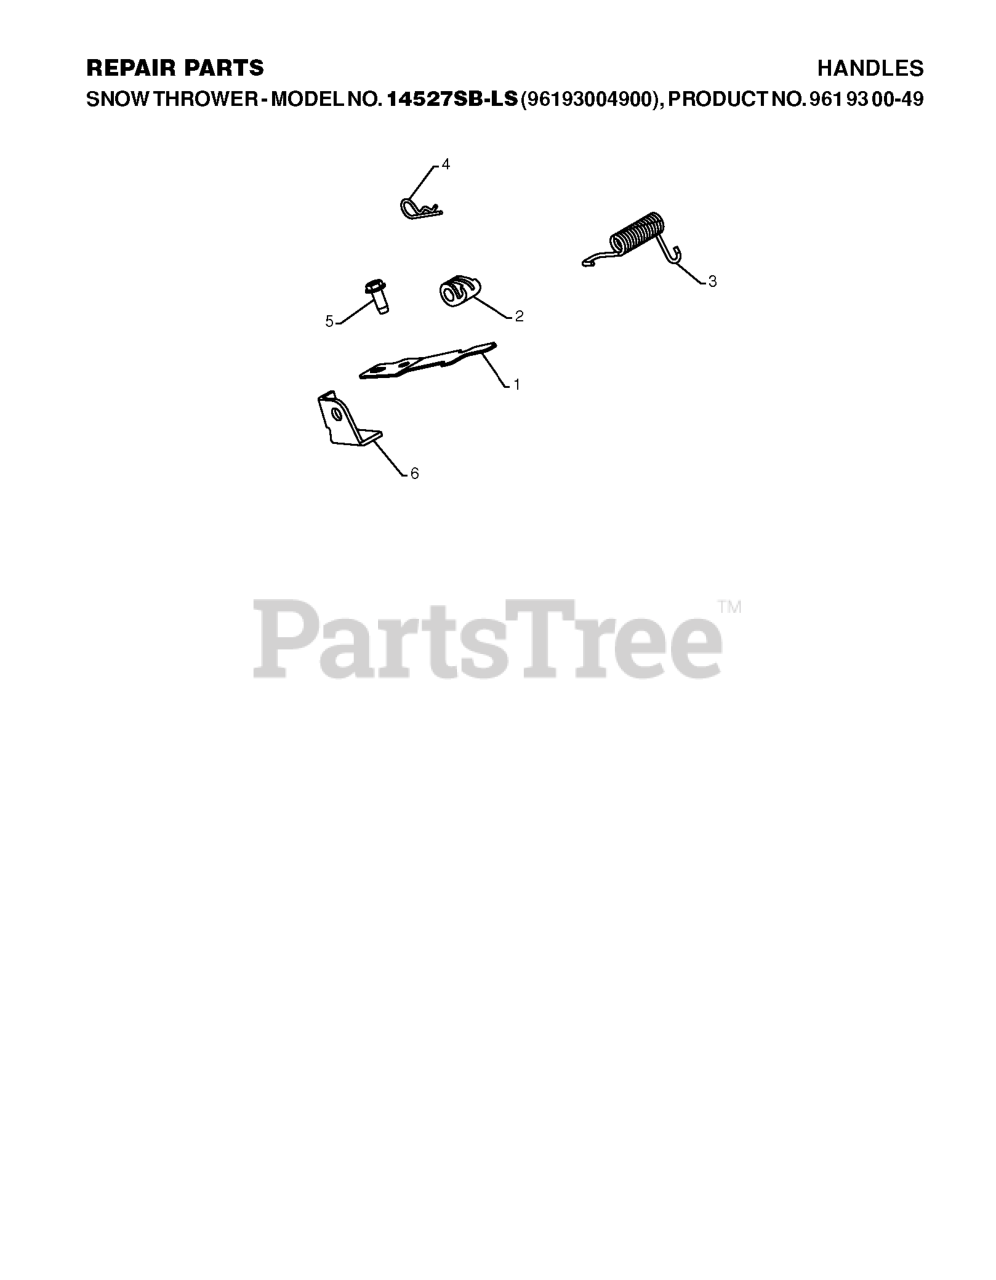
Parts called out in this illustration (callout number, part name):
1	RP SPRING.INTERLOCK
2	CAM.INTERLOCK.RELEASE
3	RP SPRING, TORSION
4	SPRING RETAINER
5	SCREW 14-20 X 5/8
6	STOP.INTERTLOCK.SPRING.
